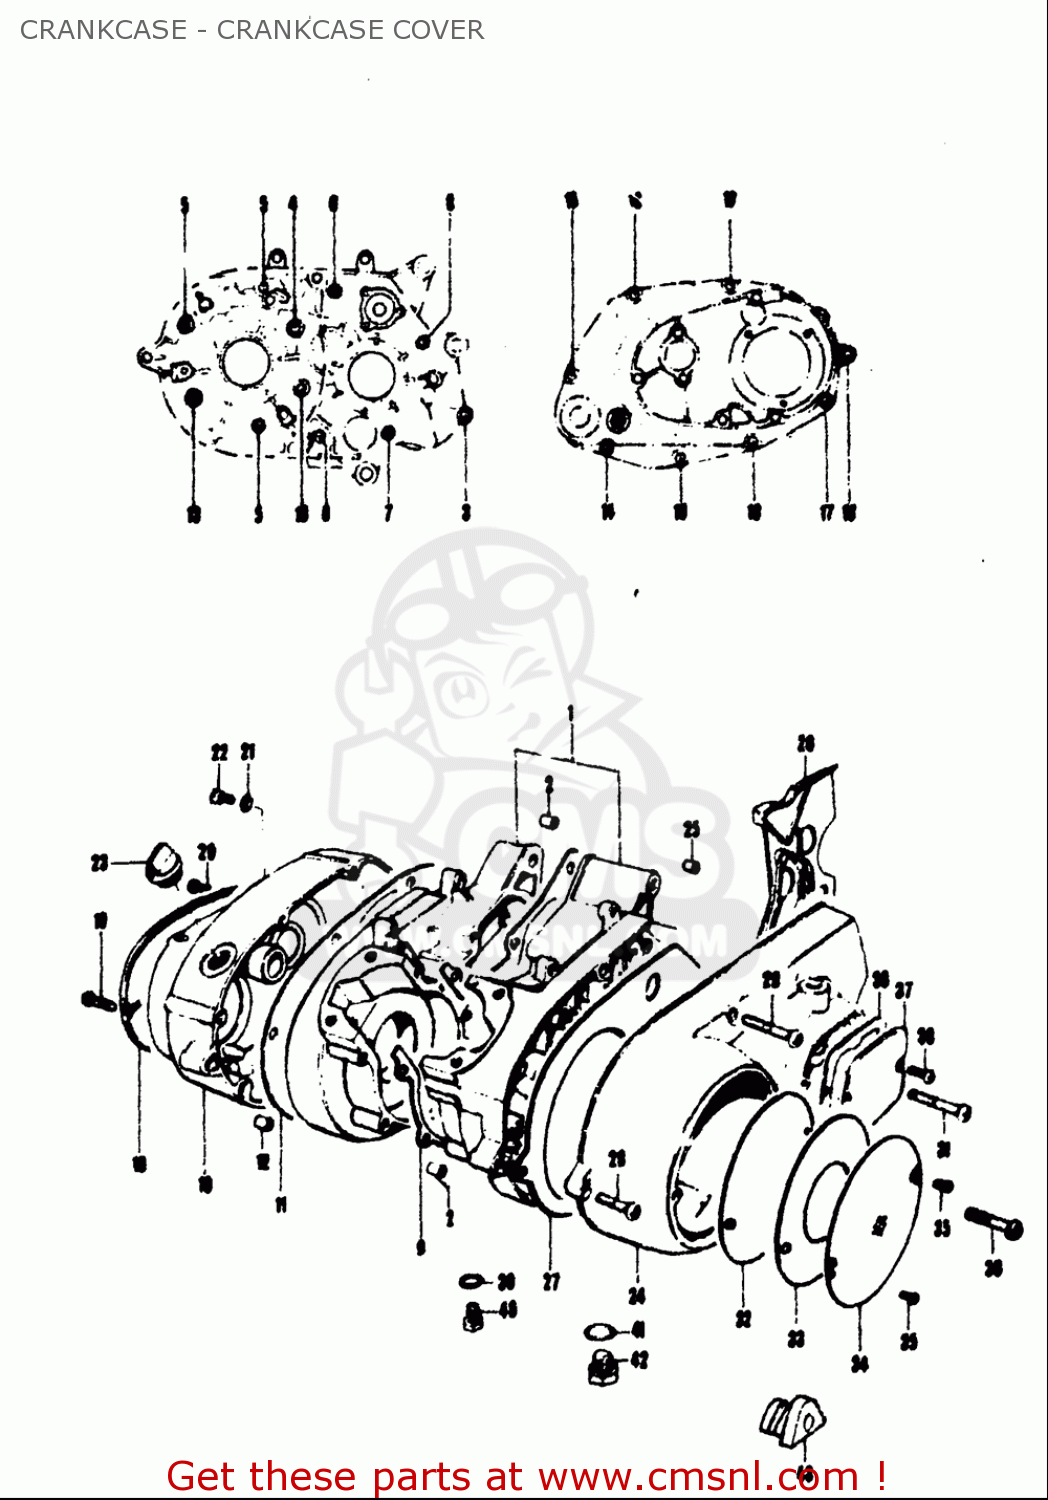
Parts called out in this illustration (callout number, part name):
2	PIN
3	SCREW
4	SCREW
5	SCREW
6	SCREW
7	SCREW
8	SCREW
9	GASKET,CRANKCASE (NAS)
11	GASKET,CLUTCH COVER
12	PIN
13	SCREW
14	SCREW
15	SCREW
16	SCREW
17	SCREW
18	COVER,OIL PUMP
19	SCREW
21	GASKET(6.2X11X1) (NAS)
23	PLUG SET
25	PIN
36	GROMMET,STARTING MOTOR
38	SCREW
39	GASKET(10X14X3.6) (NAS)
40	PLUG
41	GASKET(14X19.2X2) (NAS)
42	PLUG(MAGNETO)
